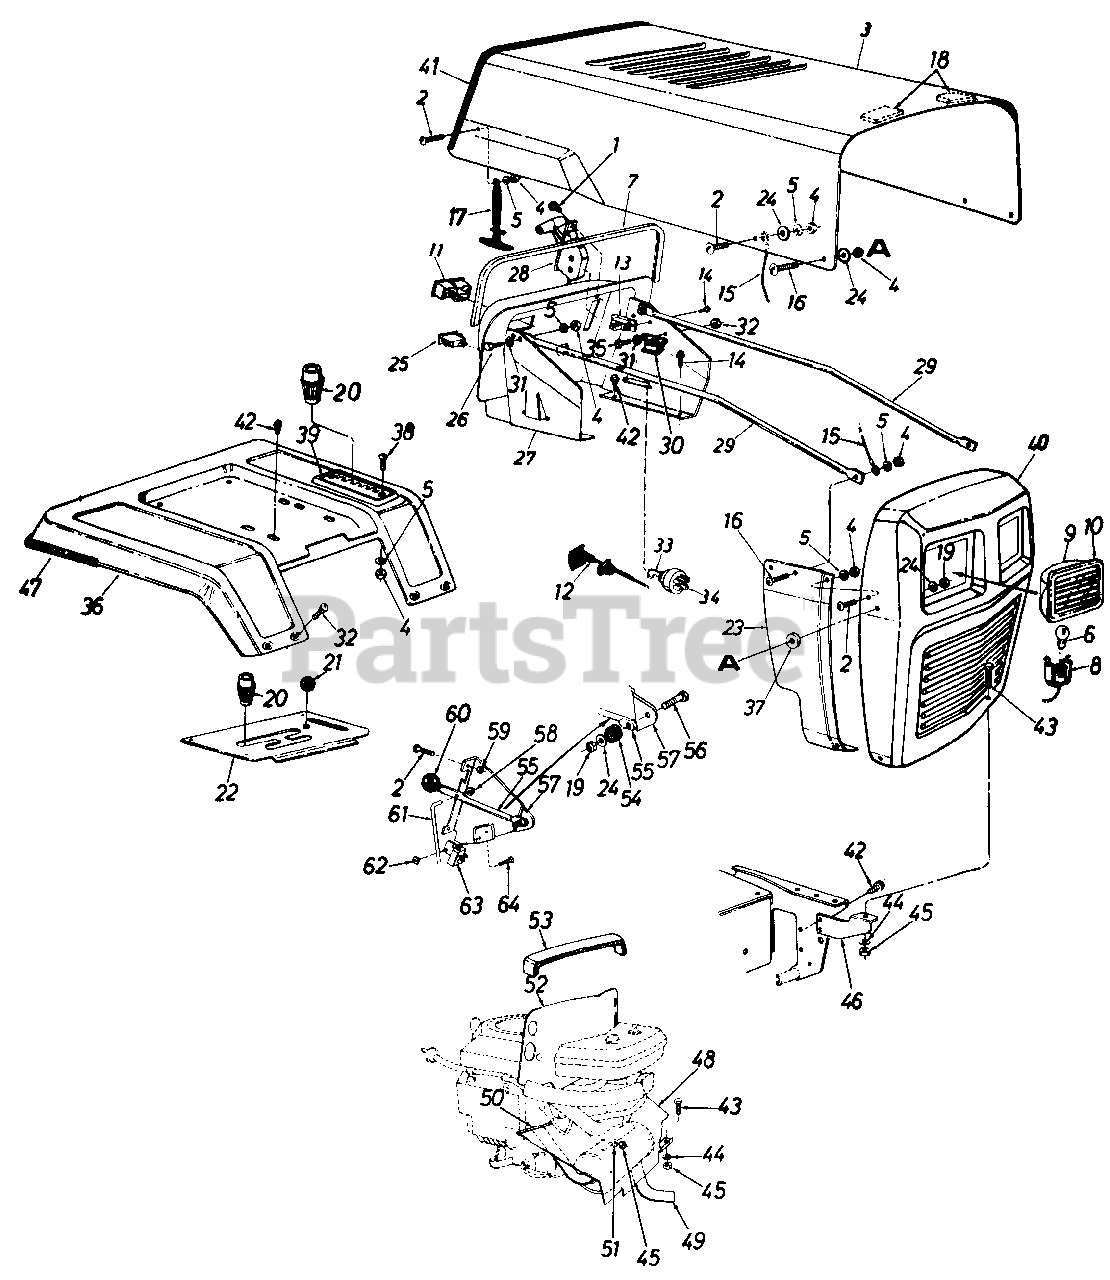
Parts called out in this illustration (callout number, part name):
1	Truss Mach. AB-Tap Scr. #10 x .5" Lg.
2	Truss Mach. Scr. 1/4-20 x .5" Lg.*
5	L-Wash. 1/4" I.D.
6	Lamp
7	Trim Strip 29" Lg.
8	Socket
9	Headlight Housing
10	Lens
11	Ammeter
12	Choke Control 46" Lg.
13	Circuit Breaker 8 Amp
14	Hex Tap Scr. #10 x .5 Lg.
15	Hood Stop
16	Truss Mach. Scr. 1/4-20 x .75" Lg.
17	Hood Latch Ass'y.
18	Foam Strip
19	Hex Patch L-Nut 1/4-20 Thd.
20	Shift Knob
21	Ball Knob Brake
22	Transmission Cover
23	Grille Side Panel R.H.
24	Fl-Wash. .281" I.D. x .73" O.D.
25	Light Switch
26	Truss Mach. Scr. 1/4-20 Thd.
27	Dash Panel Ass'y.
28	Throttle Control Box Ass'y.
29	Grille Support Rod
30	Solenoid
31	Ext. L-Wash. 1/4" I.D.
32	Carriage Bolt 1/4-20 x .5" Lg.
33	Ignition Key
34	Ignition Switch
35	Hex Bolt 1/4-20 x .5" Lg.
36	Rear Fender
37	Rubber Washer
38	Truss Mach. Scr. 1/4-20 x .62" Lg.
39	7-Speed Index Brkt.
42	Hex Wash. AB-Tap Scr. 5/16 x .75" Lg.
43	Hex Bolt 5/16-18 x .75" Lg.
44	L-Wash. 5/16" I.D.
45	Hex Nut 5/16-18 Thd.
46	Grille Mtg. Bracket R.H.
47	Trim Strip 81" Lg.
48	Front Heat Shield
49	Muffler
50	Trim Strip 10" Lg.
51	Spec. L-Wash. 5/16" I.D.
52	Top Heat Shield
53	PVC Foam
54	Rubber Washer
55	PTO Lever
56	Hex Bolt 1/4-20 x 1.25" Lg.
57	Deck Clutch Control Brkt.
58	Push Cap
59	Hex Sems Nut 1/4-20 Thd.
60	Knob Blade Clutch
61	Deck Control Rod
62	Hex Nut #10-24 Thd.
63	Safety Switch
64	Truss Mach. Scr. #10-24 x .5"Lg.
